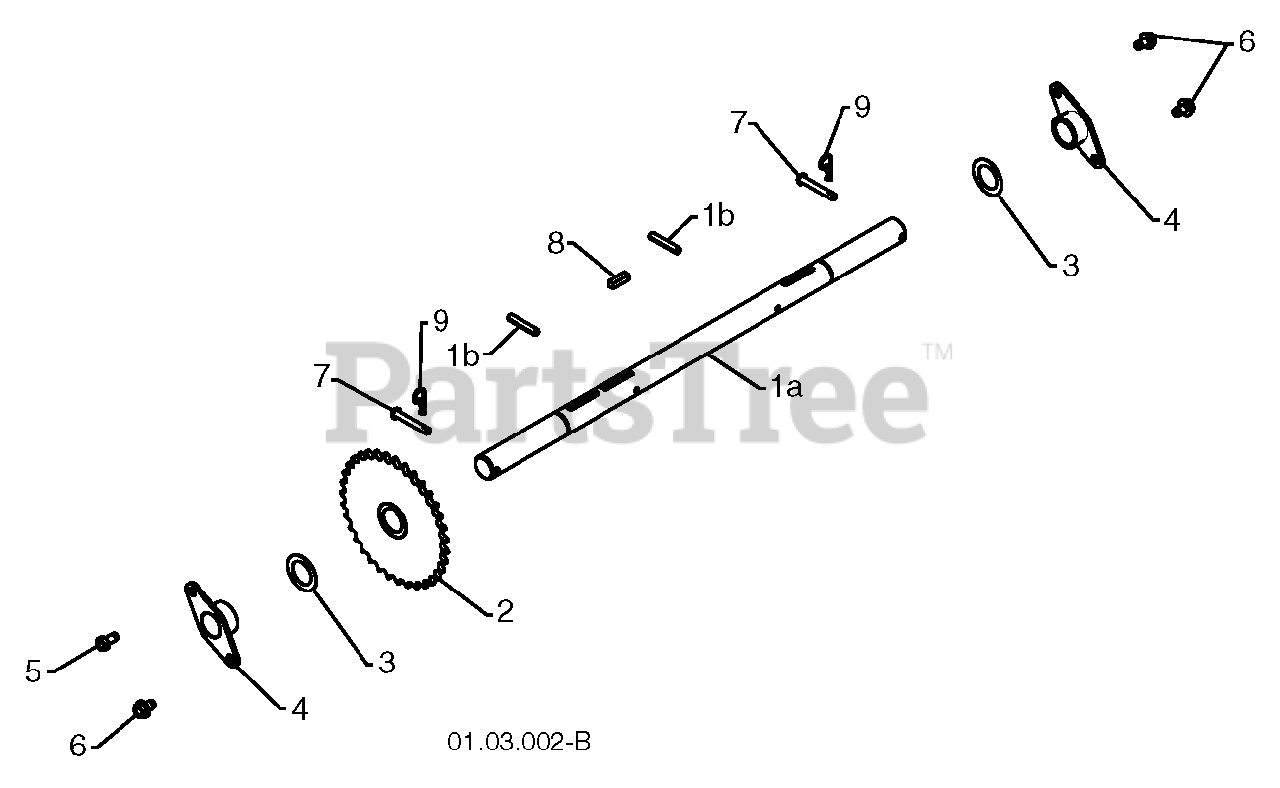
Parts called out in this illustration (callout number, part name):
1	AXLE.ASM.SHAFT.W/ROLLPIN.PS
1A	SHAFT.AXLE.POWER.STEERING
1B	PIN.ROLL.3/16
2	SPROCKET.WELDMENT.AXLE.1.00
3	WASHER 1.00
4	BEARING, AXLE
7	RIVET
8	KEY, SQUARE 1/4 X .875
9	RETAINER M
